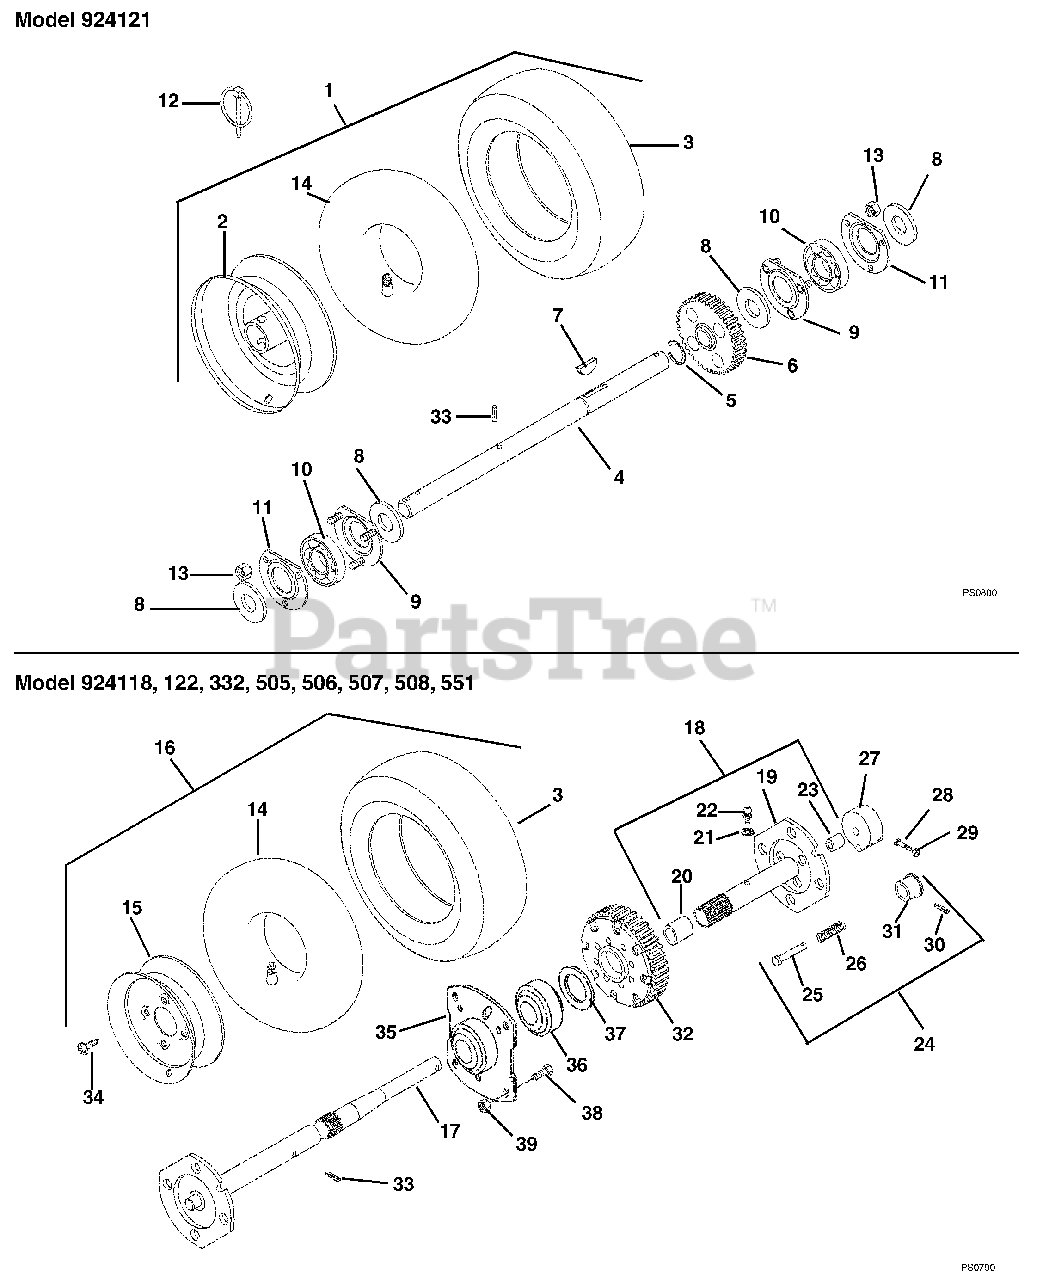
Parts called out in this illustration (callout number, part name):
1	TIRE/WHEEL ASSEMBLY 16X6.50-8
2	WHL 6.50X8
3	TIRE 4.80-8 NHS
3	TIRE 16X6.50-8 SNO-HOG TREAD
4	SHAFT, AXLE
5	RG-RTNG-EXT. .875X.050
6	GEAR, SPUR
7	KEY-WDRF .25X.875X.375 SAE A
8	WSHR-FL-STL .880X1.250X.062YWZ
9	BEARING FLANGE
10	BRG-BALL .876 X 1.750 X .50
11	BEARING FLANGE
12	PIN-LOK .31X1.75
13	@NUT-LK-CTR .25-20 YWZC
14	TUBE
15	WHL
16	T/WHL ASSY 4.80-8
16	T/WHL ASSY 16X6.50-8 SNO-HOG
17	AXLE, RH
18	L.H. AXLE ASSEMBLY
18	L.H.AXLE ASSEMBLY
19	L H AXLE
20	BSHG-SLV .750X.814X .750 BRZ
21	WSHR-LK .250X.047 LT YWZC
22	FTG-LUBE .25-28X.256 YWZC
23	BSHG-SLV .562X.625X.625 BRZ
24	LOCKOUT HUB ASSEMBLY
25	PIN
26	SG-COMP .028X.34X1.062 WLD75
27	LOCKOUT HUB
28	BLT-HEX .25-20X2.0 PL GR8 YWZC
29	NUT-JAM-NYL .250-20 W/INSERTYZ
30	PIN-ROLL .093X1.00
31	KNOB
32	DIFFERENTIAL ASSEMBLY
33	PIN-ROLL .188X1.50
34	SCR-TAP .500-20X.62 HH YWZC
35	BEARING RETAINER
36	BRG-BALL 1.13X2.19X.63
37	WSHR-FL-STL 1.140X1.718X.134YZ
38	BLT-SERNK SL .25-20X.50 YWZC
39	@NUT-SPNLK-FLG .25-20 YWZC
